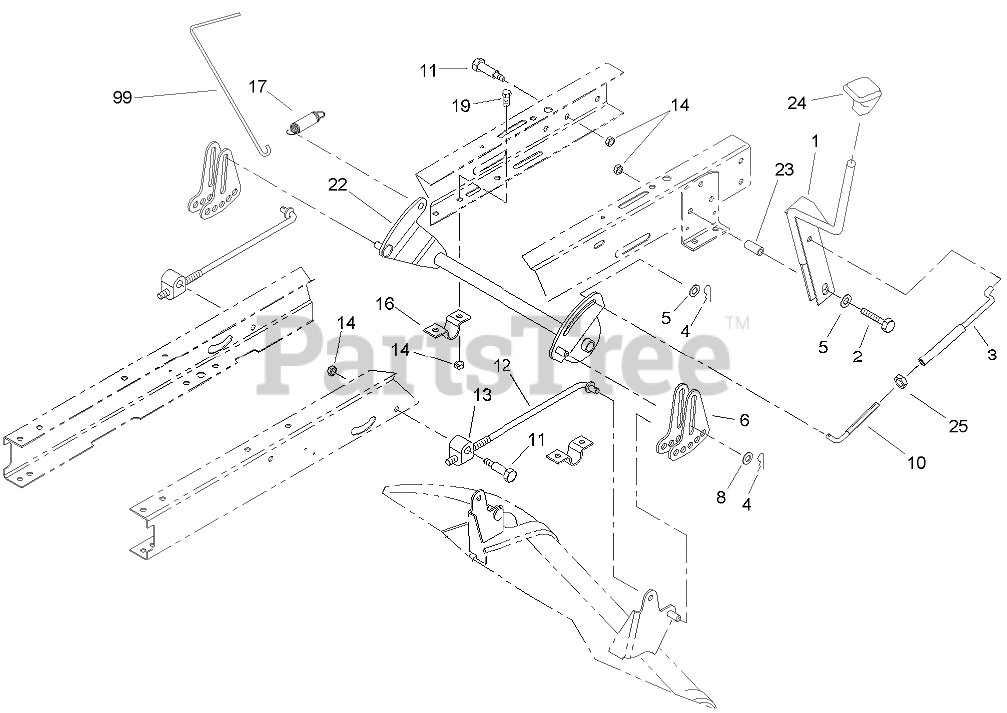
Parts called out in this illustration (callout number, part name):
1	HOC LEVER ASM
2	SCREW-HH
4	PIN-COTTER
5	WASHER-FLAT
6	LINK-ADJUSTING, HOC
8	WASHER-HARDENED
10	LINK-HOC
11	SCREW-SHOULDER, HH
12	ROD-HANGER, REAR
13	TRUNNION-HOC
14	NUT-LOCK, NI
16	CLAMP-PIVOT, HOC
17	SPRING-EXTENSION
19	SCREW-HH
22	PIVOT-HOC
23	SPACER
24	KNOB-SHIFT
25	NUT-JAM
99	TOOL - SPRING
